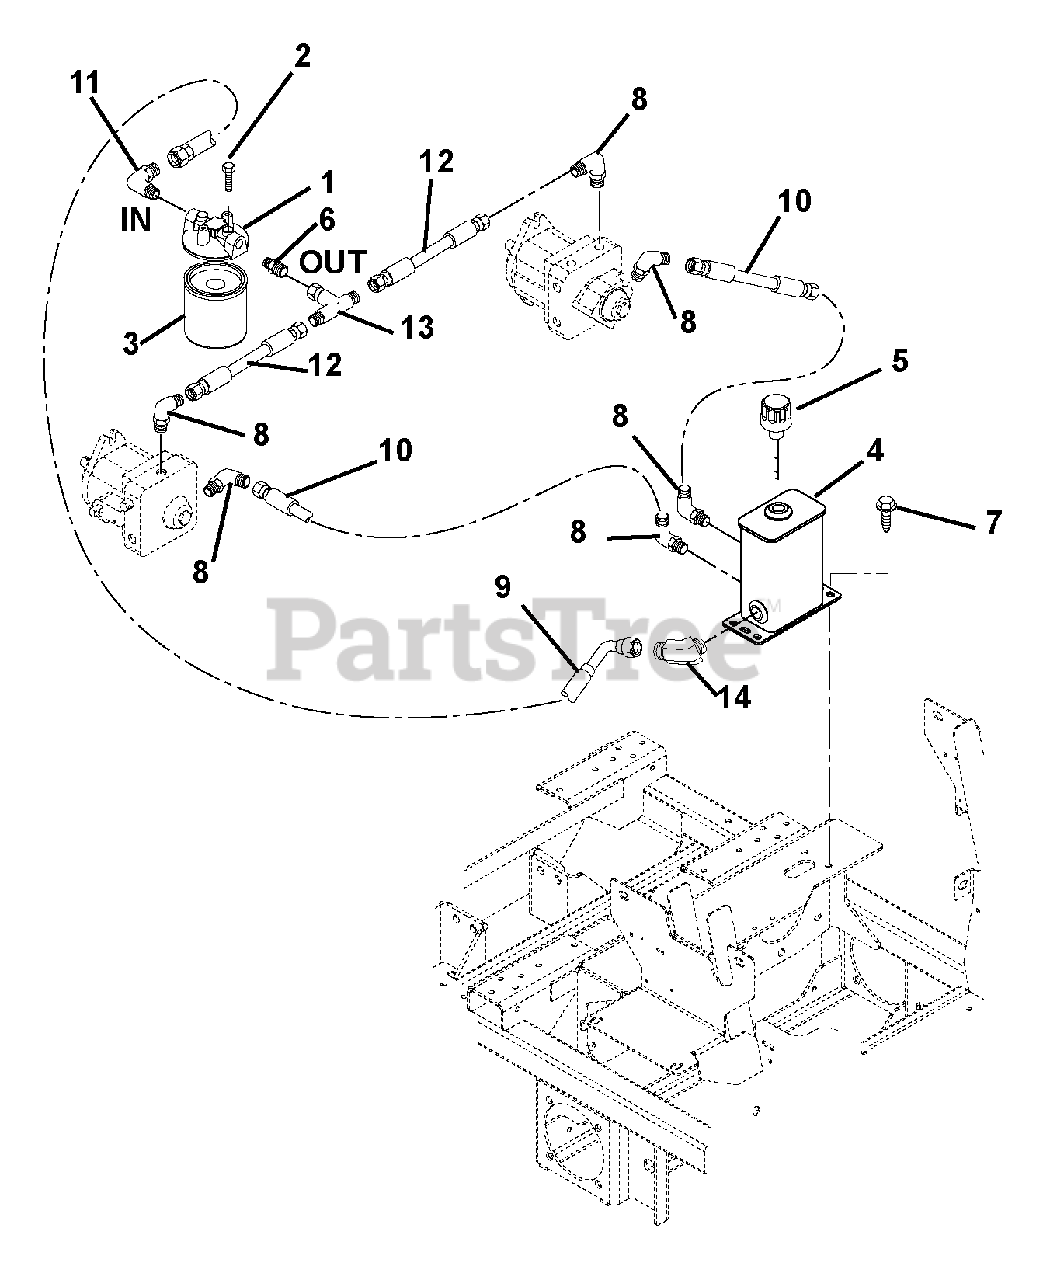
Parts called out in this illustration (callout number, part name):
1	Filter Housing
2	Bolt-Hex .25-20 x .50 Grade 5 Epoxy
3	Filter Element
4	Body, Hydraulic Tank
5	Breather, Dipstick
6	Fitting, Hydraulic, Straight Steel
7	Screw-Tapping .38-16 x .75 Hex Washer Head
8	Fitting, Hydraulic, 90 Degree Elbow
9	Hose-Hydraulic Valve to Tank
10	Hose, Hydraulic, 10-inch
11	Fitting, Hydraulic, 90 Degree Elbow
12	Hose, Hydraulic .50, 5-Inch
13	Fitting, Hydraulic Tee
14	Fitting, Hydraulic .45 Degree Elbow
